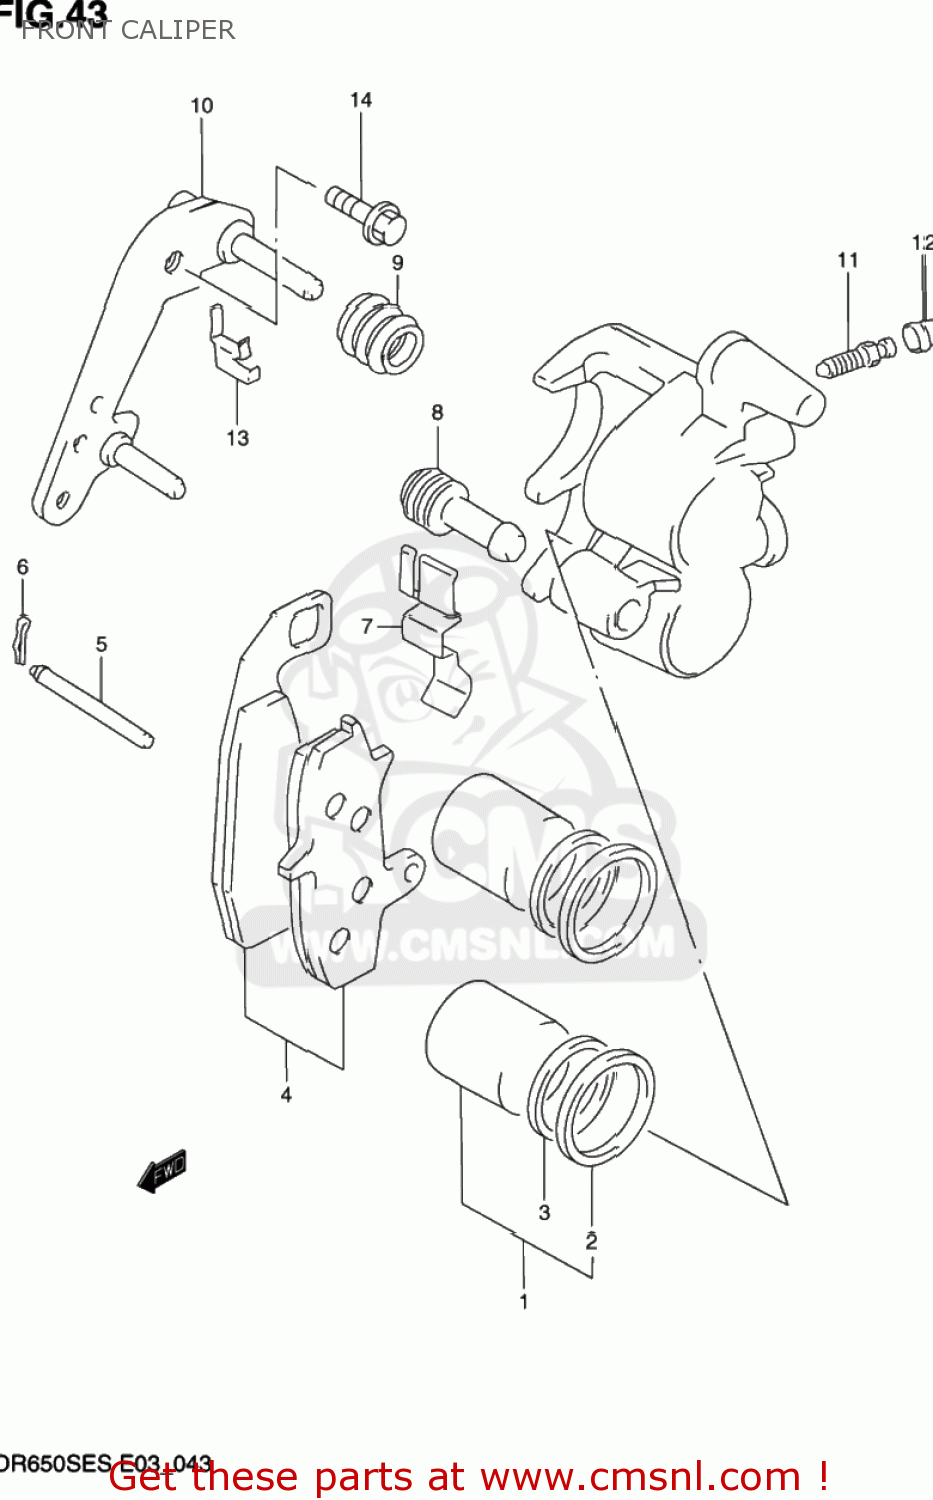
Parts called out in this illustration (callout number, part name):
1	PISTON SET
2	SEAL,PISTON
3	SEAL,WIPER
4	PAD SET (NAS)
5	PIN,PAD
6	CLIP,PAD PIN
7	SPRING,PAD
8	INSULATOR,AXLE
9	BOOT,AXLE
10	BRACKET
11	BLEEDER
12	CAP,BREATHER
13	GUIDE,PAD
14	BOLT
